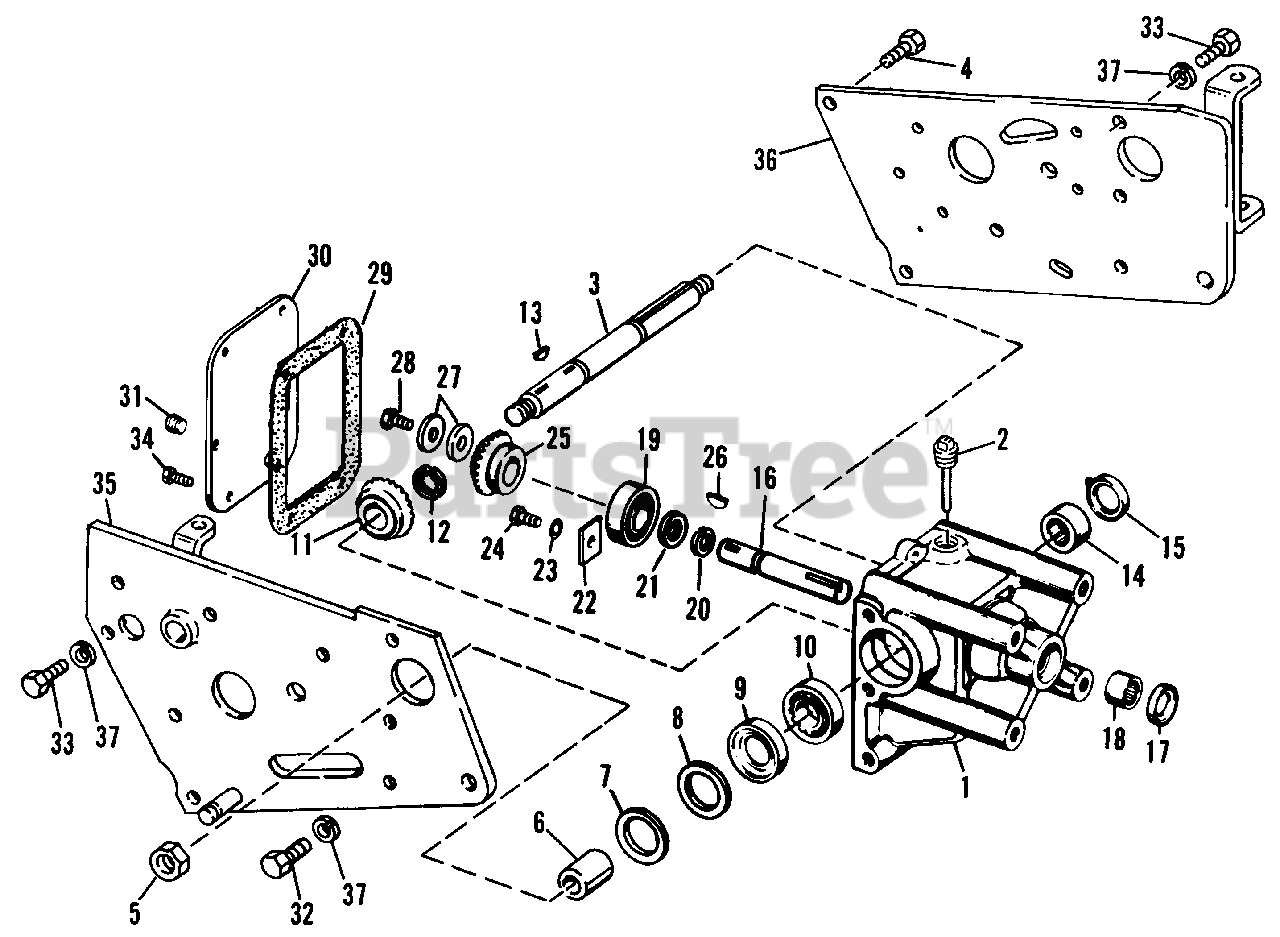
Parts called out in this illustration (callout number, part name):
1	Bevel Gear Housing, w/Bearings
2	Plug Assy., Oil Fill
3	Driven Shaft
4	Hex Capscrew, 7/16"-14 x 1-1/4"
5	Hex Jam Nut
7	Shim (As Required)
10	Ball Bearing
11	Bevel Driven Gear
12	Retaining Ring
14	Needle Bearing
16	Drive Shaft
18	Needle Bearing
19	Ball Bearing
20	Retaining Ring
22	Bearing Clamp Plate
23	Lockwasher, 5/16"
24	Hex Capscrew, 5/16"-18 x 5/8"
25	Bevel Driven Gear
27	Washer, Compression
28	Hex Capscrew, 5/16"-18 x 3/4"
30	Housing Cover Assembly
31	Pipe Plug
32	Hex Capscrew, 7/16"-14 x 1"
33	Hex Capscrew, 7/16"-14 x 1-1/4"
34	Hex Capscrew, 1/4"-20 x 5/8"
35	Right Hand Side Plate Assy.
36	Left Hand Side Plate Assy.
37	Lockwasher, 7/16"
